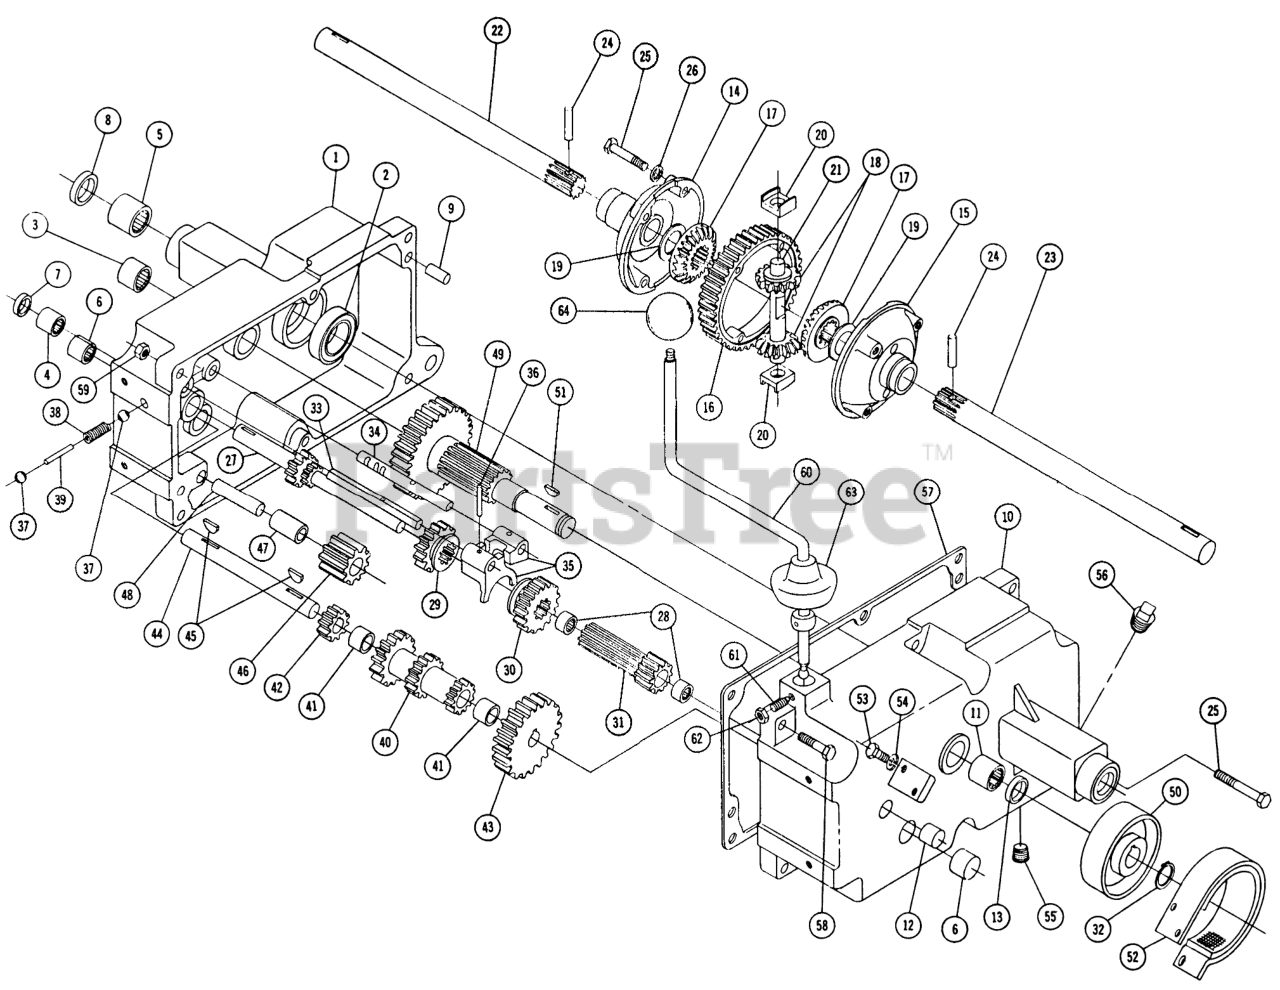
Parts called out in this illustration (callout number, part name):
1	Case R.H.
3	BEARING-NEEDLE
6	BEARING-NEEDLE
9	PIN-DOWEL
14	DIFF CASE RH
16	GEAR DIFF BULL
20	BLOCK
25	Bolt Hex 3/8-16 x 1
26	Lockwasher-3/8 Int. Tooth
28	BEARING-NEEDLE
29	GEAR-HI AND 2ND
30	GEAR-LOW AND REVERSE
31	GEAR
33	RAIL-SHIFT
34	Rail-Rear Shift
35	FORK-SHIFT
36	PIN-ROLL
37	BALL-DETENT
39	PIN-SHIFT
41	BUSHING-BRONZE
43	GEAR-CLUSTER SHAFT
45	Key
46	GEAR/BUSHING ASM-REVERSE IDLER
47	BUSHING
48	PIN-DIFFERENTIAL
51	KEY-WOODRUFF
53	Bolt-1/4-20 x 5/8
54	Lockwasher
57	GASKET-TRANSMISSION
58	Bolt, 3/8 16 x 2
61	SETSCREW
62	Nut-Nylok
63	COVER-DUST
